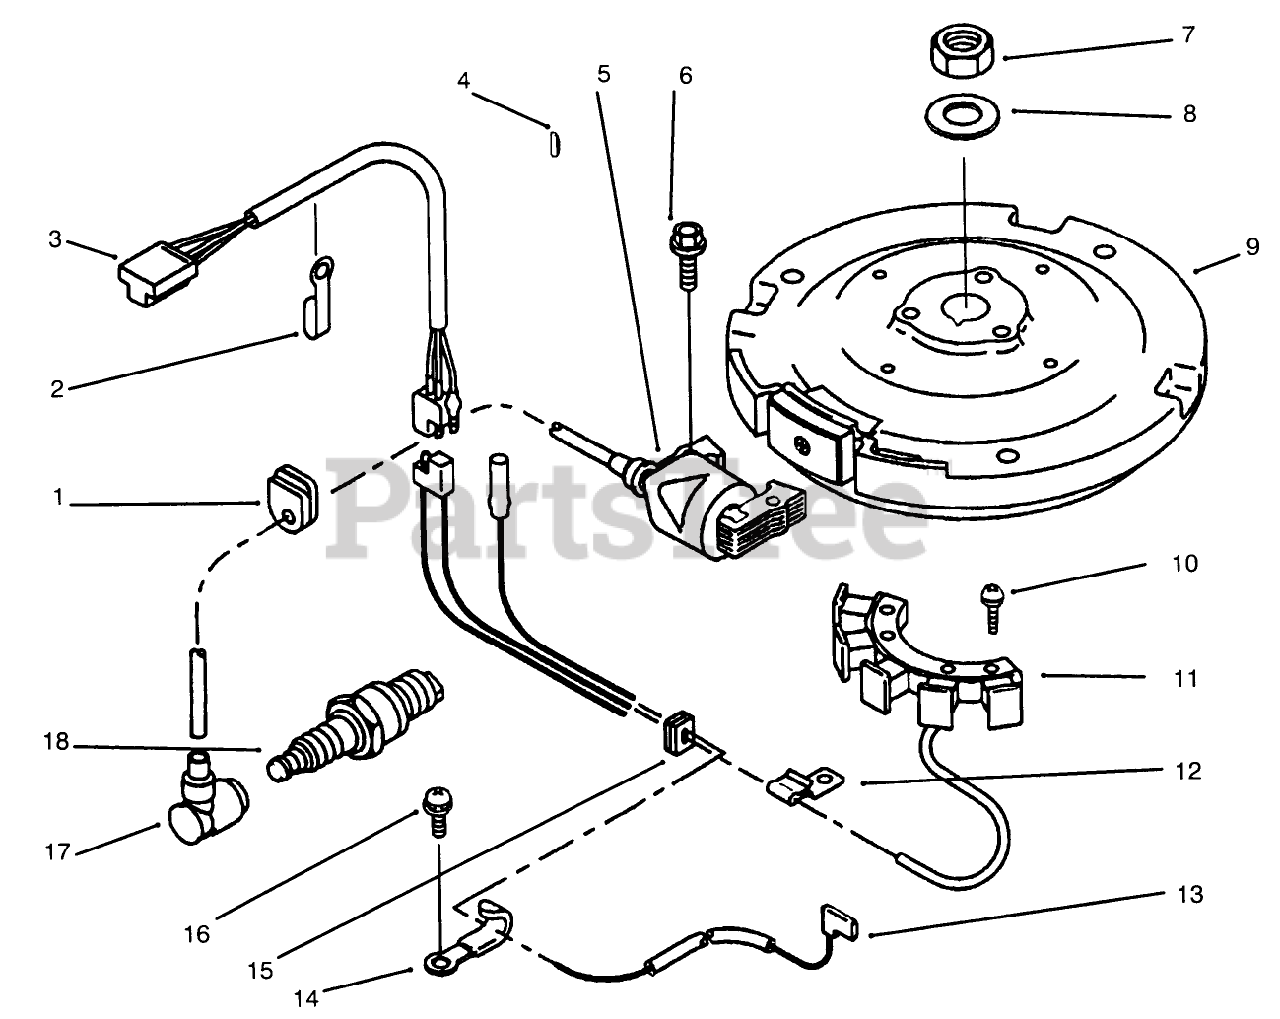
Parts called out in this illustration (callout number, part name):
1	Grommet
2	Clamp
3	Harness
4	Key
5	Coil-Ignition
6	Bolt-Flange
7	Nut
8	Washer
9	Flywheel
10	Screw
11	Coil-Charging
12	Clamp
13	Wire-Lead
14	Clamp
15	Grommet
16	Screw
17	Cap-Spark
18	Spark Plug-Rcj8
